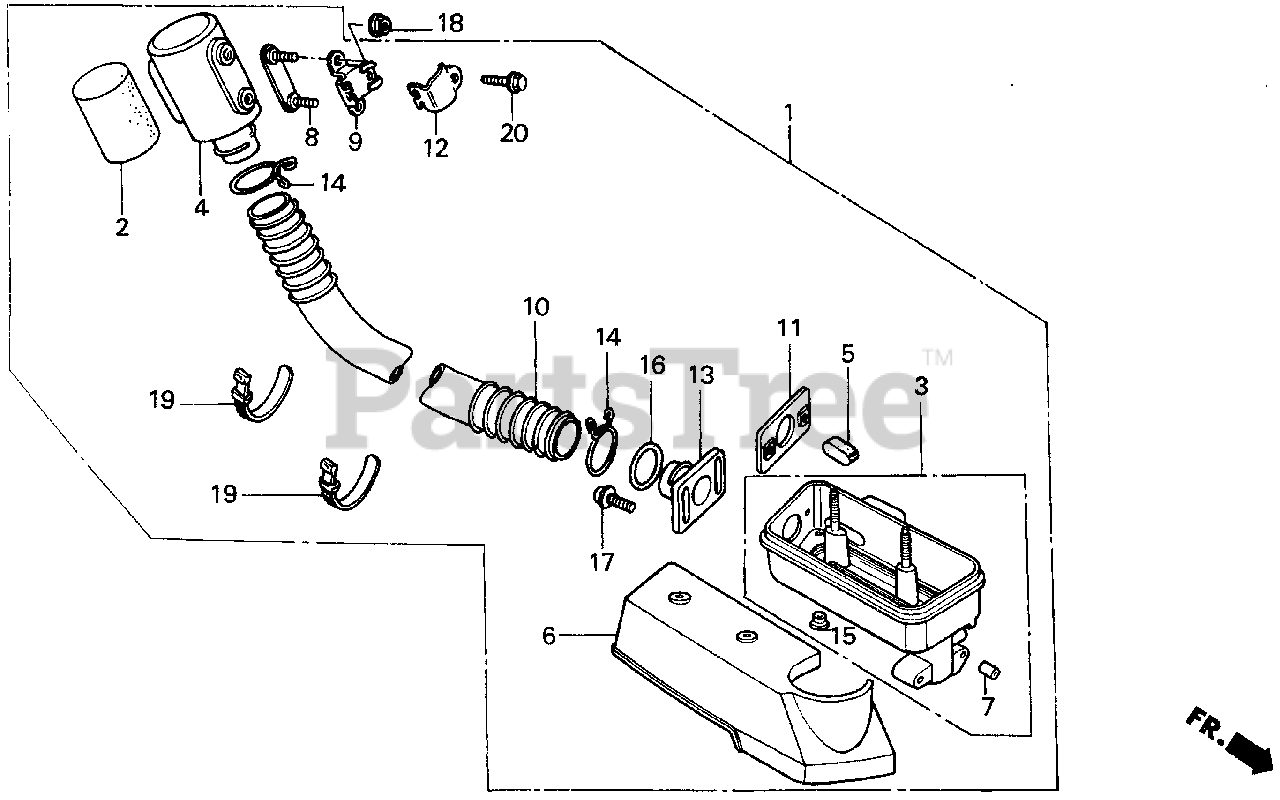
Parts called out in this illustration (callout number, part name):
1	AIR CLEANER KIT, SNORKEL *R8*
2	ELEMENT, AIR CLEANER
3	HOUSING, AIR CLEANER Use from Engine SN 2085824.
4	HEAD, SNORKEL AIR CLEANER
5	CAP, SNORKEL AIR CLEANER
6	COVER, AIR CLEANER *R8*
7	COLLAR, AIR CLEANER
8	PLATE, AIR CLEANER SETTING
9	BRACKET A, AIR CLEANER
10	HOSE, SNORKEL AIR CLEANER
11	FLANGE, SNORKEL PIPE
12	BRACKET B, AIR CLEANER
13	PIPE, SNORKEL
14	CLIP, AIR HOSE (27) (NOT AVAILABLE)
15	COLLAR, GEARSHIFT LEVER SETTING
16	O-RING (27.7X1.9)
17	SCREW-WASHER (4X10)
18	NUT, FLANGE (6MM)
19	BAND B3, CABLE HARNESS
20	BOLT, FLANGE (6X16) Use from Engine SN 2056820.
